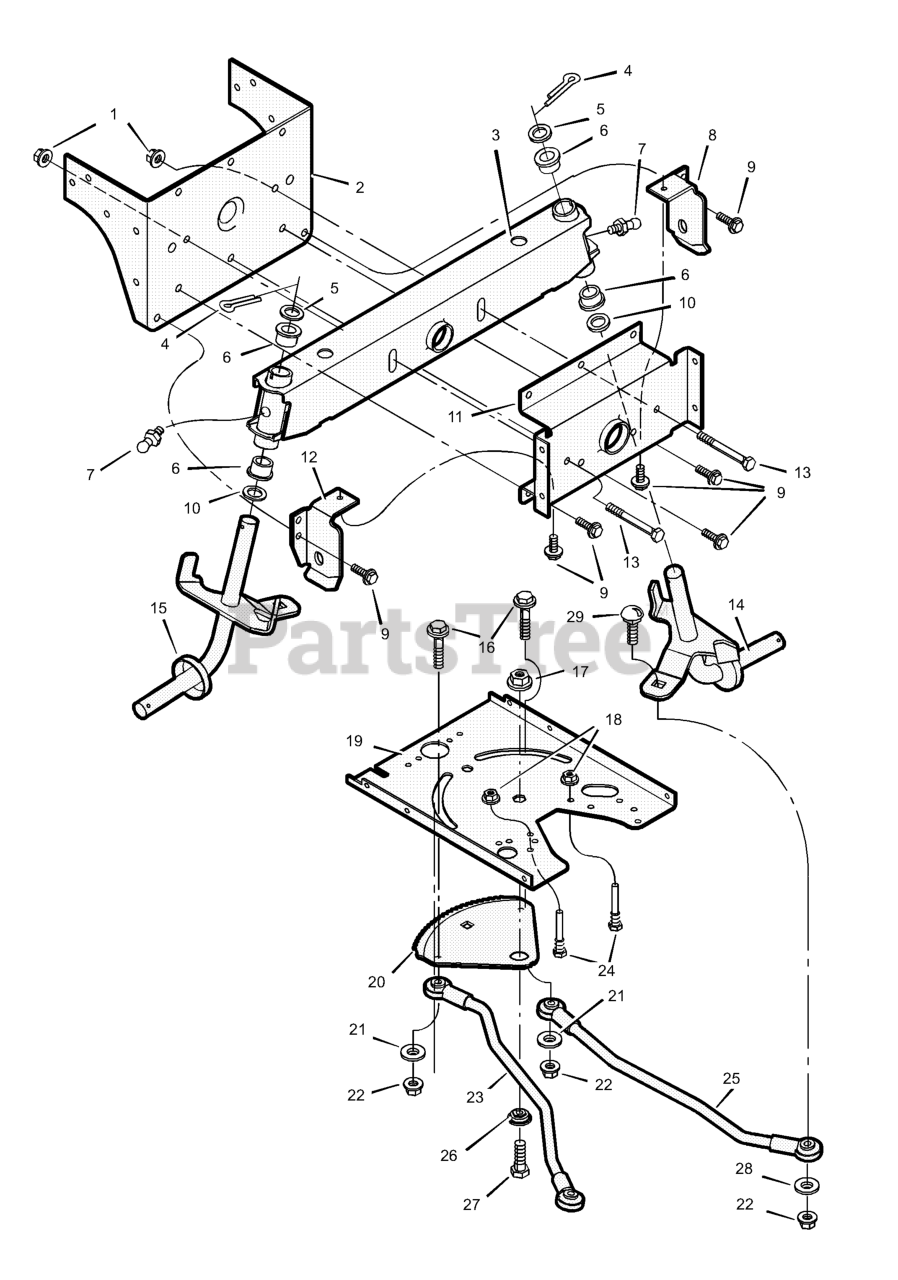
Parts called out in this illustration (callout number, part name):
1	Locknut, Flange
2	Bracket, Rear Hanger
3	Assembly, Axle (with Zerk)
4	Pin, Cotter
6	Bearing, Spindle
7	Fitting, Grease
8	Hanger, Left Deck
11	Hanger, Axle
12	Hanger, Right Deck
13	Bolt, Hex
14	Assembly, Left Spindle
15	Assembly, Right Spindle
16	Bolt, Shoulder
17	Locknut, Flange
18	Locknut, Flange
19	Plate, Steering Mount
20	Gear, Sector
22	Nut, Flange Centerlock
23	Link, Drag -Right
24	Guide, Belt
25	Link, Drag -Left
26	Bearing, Sector Gear
27	CAPSCREW, Hex Head, 5/16-18 x 1
28	Washer
29	Bolt, Carriage
